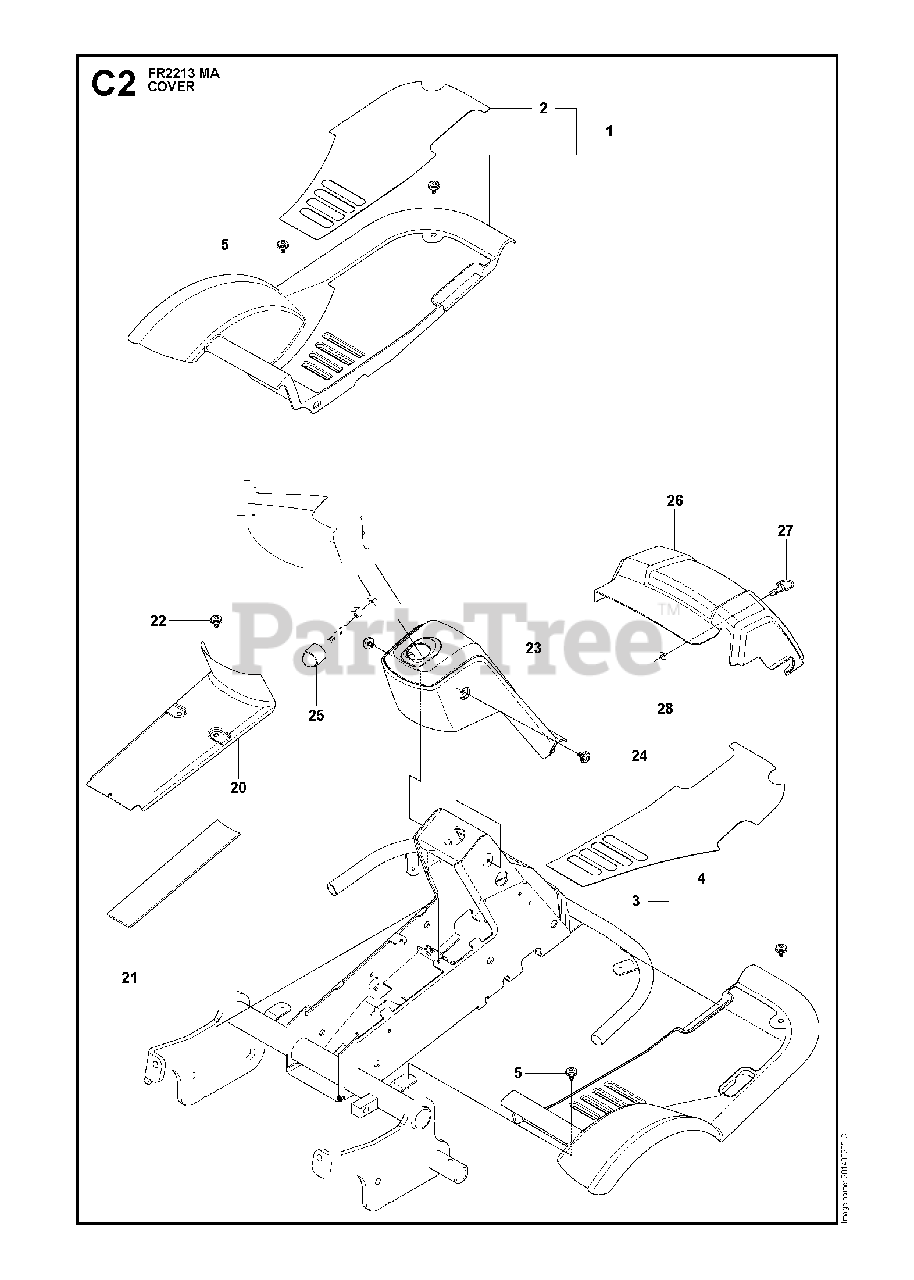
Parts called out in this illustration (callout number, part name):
5	SCREW
9	RIVET
11	BUTTON
12	SUPPORT STRAP
16	NUT
17	SCREW
19	SCREW
21	MAT
22	SCREW
24	SCREW
27	BOLT
28	WASHER
